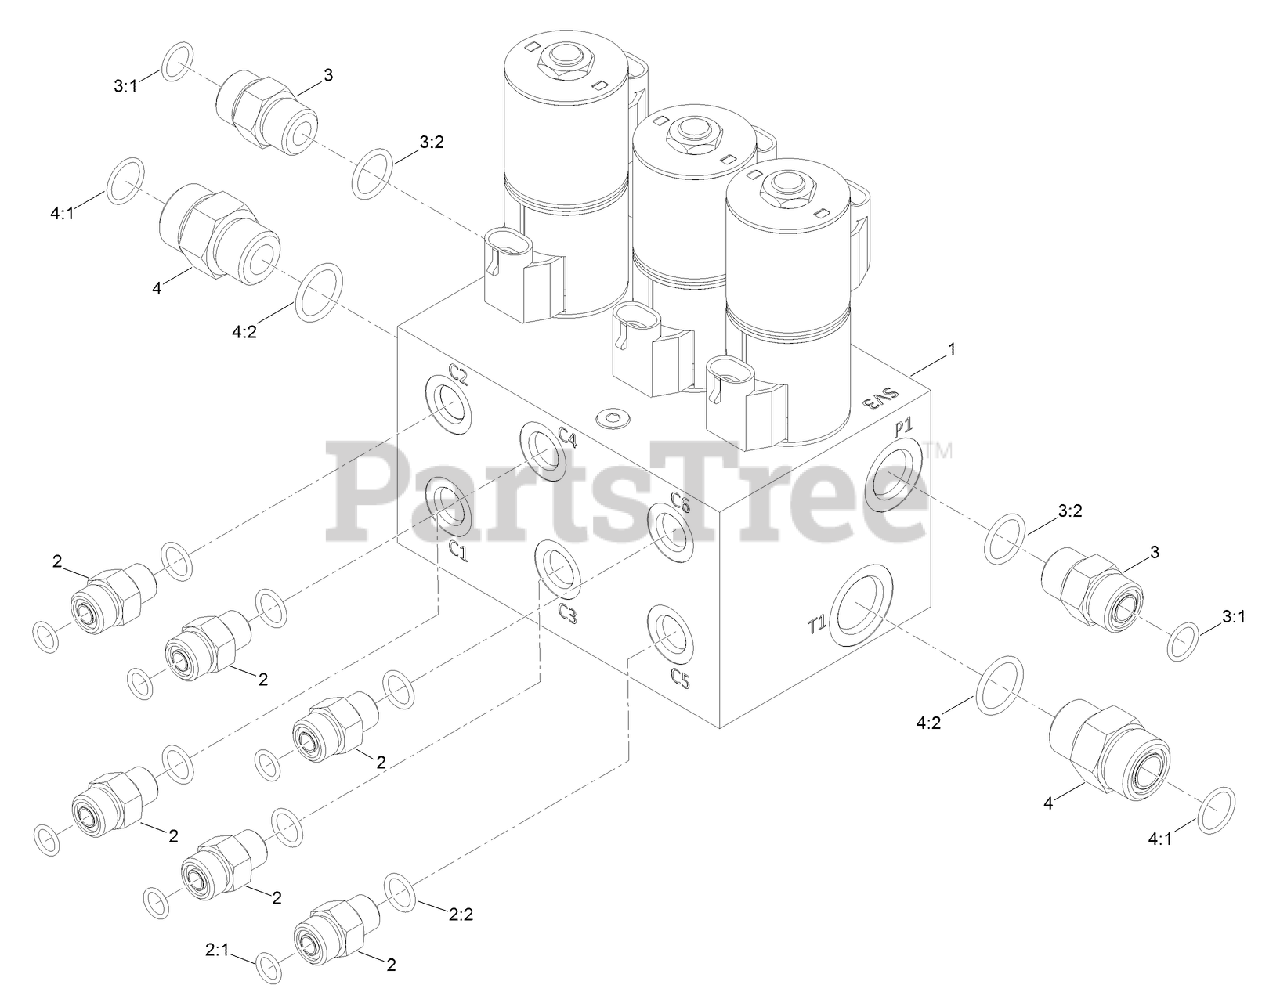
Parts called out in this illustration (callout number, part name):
1	WRENCH MANIFOLD ASM
2	FITTING-STRAIGHT
2:1	O-RING
2:2	O-RING
3	FITTING-STRAIGHT
3:1	O-RING
3:2	O-RING
4	FITTING-STRAIGHT
4:1	O-RING
4:2	O-RING
